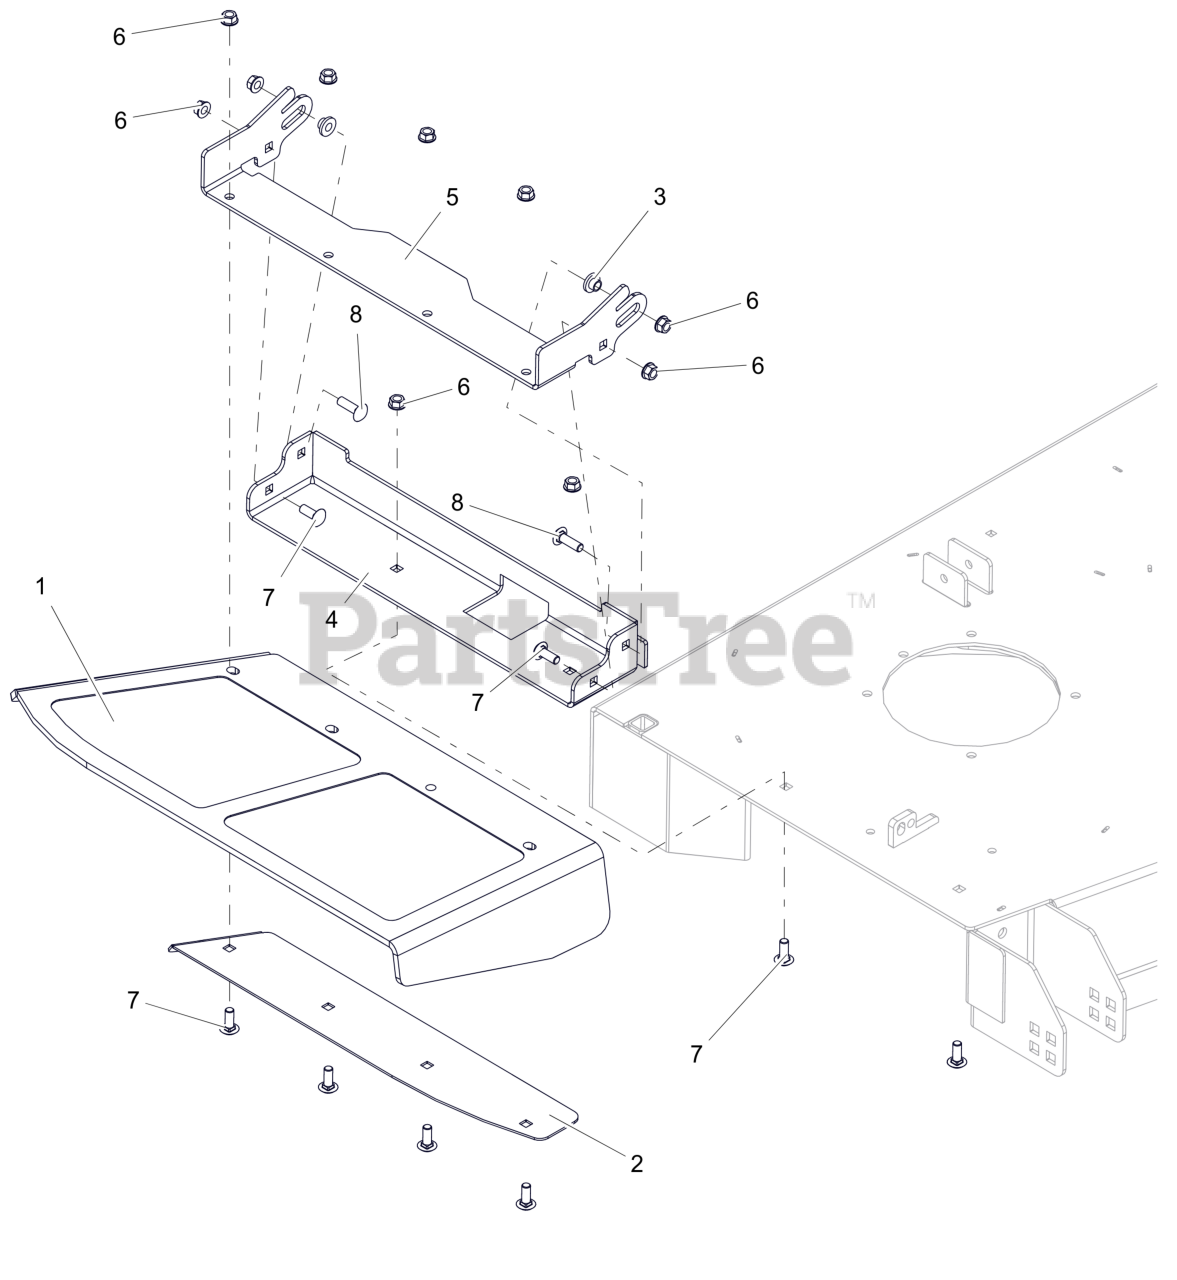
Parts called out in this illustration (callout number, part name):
1	CHUTE, FORMED RUBBER DISCHARGE
2	PLATE, DISCH CHUTE CLAMP (BLACK)
3	BSHG-FLG .385X.500X.875X.406
4	BASE- DISCHARGE CHUTE MTG
5	BRKT- CHUTE MTG
6	NUT-LK-CTR-FLG .375-16 GF ZCC
7	BLT,RHSSN .38-16X1.00 G5 ZCC
8	BLT,RHSSN .38-16X1.25 G5 ZCC
